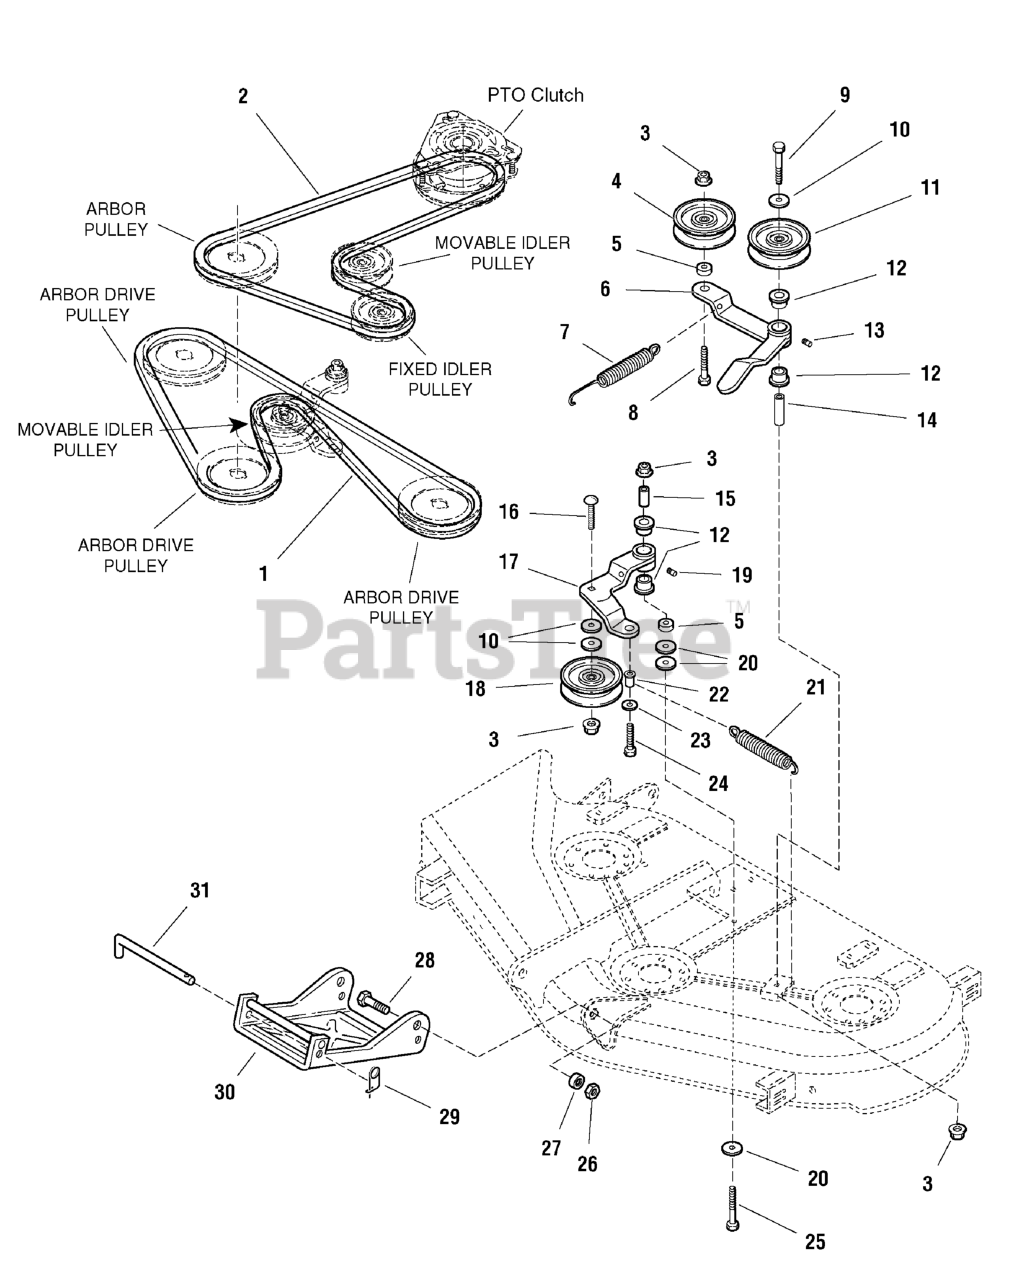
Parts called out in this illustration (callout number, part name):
1	V-BELT, Mower Drive
2	V-BELT, P.T.O.
3	NUT, Hex Flange, 3/8-16
4	PULLEY, Idler
5	SPACER, Powdered Metal
6	LEVER & HANDLE ASSEMBLY
7	SPRING, Extension
8	CAPSCREW, Hex Head, 3/8-16 x 2, G5
9	CAPSCREW, 3/8-16 x 3-1/4
10	WASHER, 3/8
11	PULLEY, Idler
13	FITTING, Lube, 1/4-20 Tapered
14	SPACER, Hardened
15	SPACER, .39 X 5/8 X 1.15
16	CARRIAGE BOLT, 3/8-16 x 1-1/4, G5
17	LEVER ASSEMBLY, Idler
18	PULLEY, Idler
19	FITTING, Lube, 1/4 Drive
20	WASHER, 3/8
21	SPRING, Extension
23	WASHER, 1/4
24	CAPSCREW, Hex Head, 1/4-20 x 1-1/6
25	CAPSCREW, Hex Head, 3/8-16 x 2-1/2, G5
26	NUT, Hex Lock ESNA Light, 3/8-16
27	SPACER, Powdered Metal
28	CAPSCREW, 3/8-16 x 1-1/4, G8
29	PIN, Retaining
30	HITCH & ROD ASSEMBLY
31	ROD, Hitch
